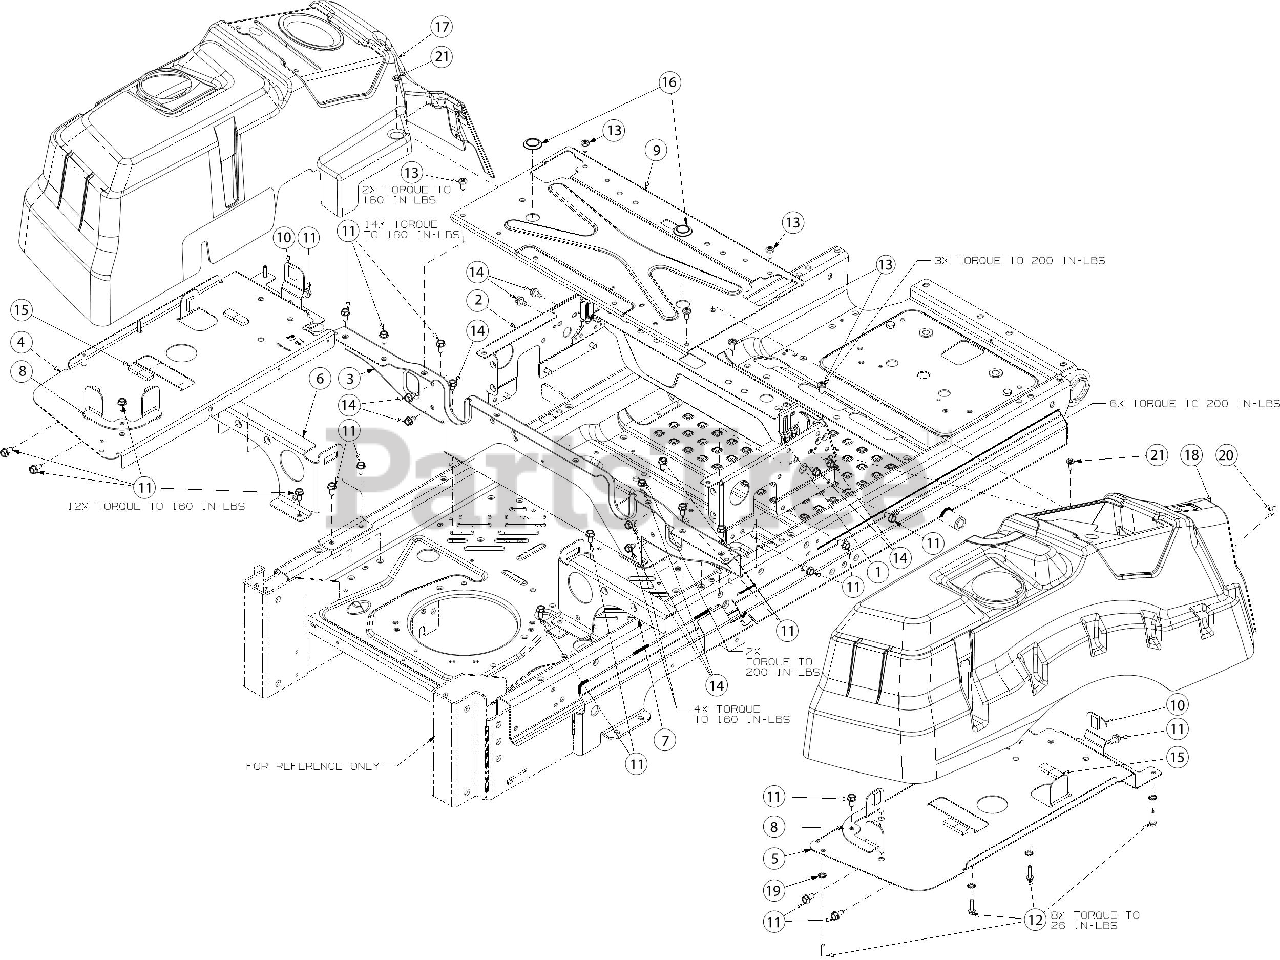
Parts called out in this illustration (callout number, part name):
11	SCREW 5/16-18 x .750
12	SCREW 5/16-14 x 1
13	SCREW 5/16-18 x .750
14	SCREW 5/16-18 x .500
15	FOAM TAPE .625 WIDE x .25 THK BULK
17	CONSOLE (LH) Z-STYLE
18	CONSOLE (RH) Z-STYLE
20	SHOULDER SCREW M6-1 .368 X.115
21	SHOULDER SCREW M6-1 .368 X.115
